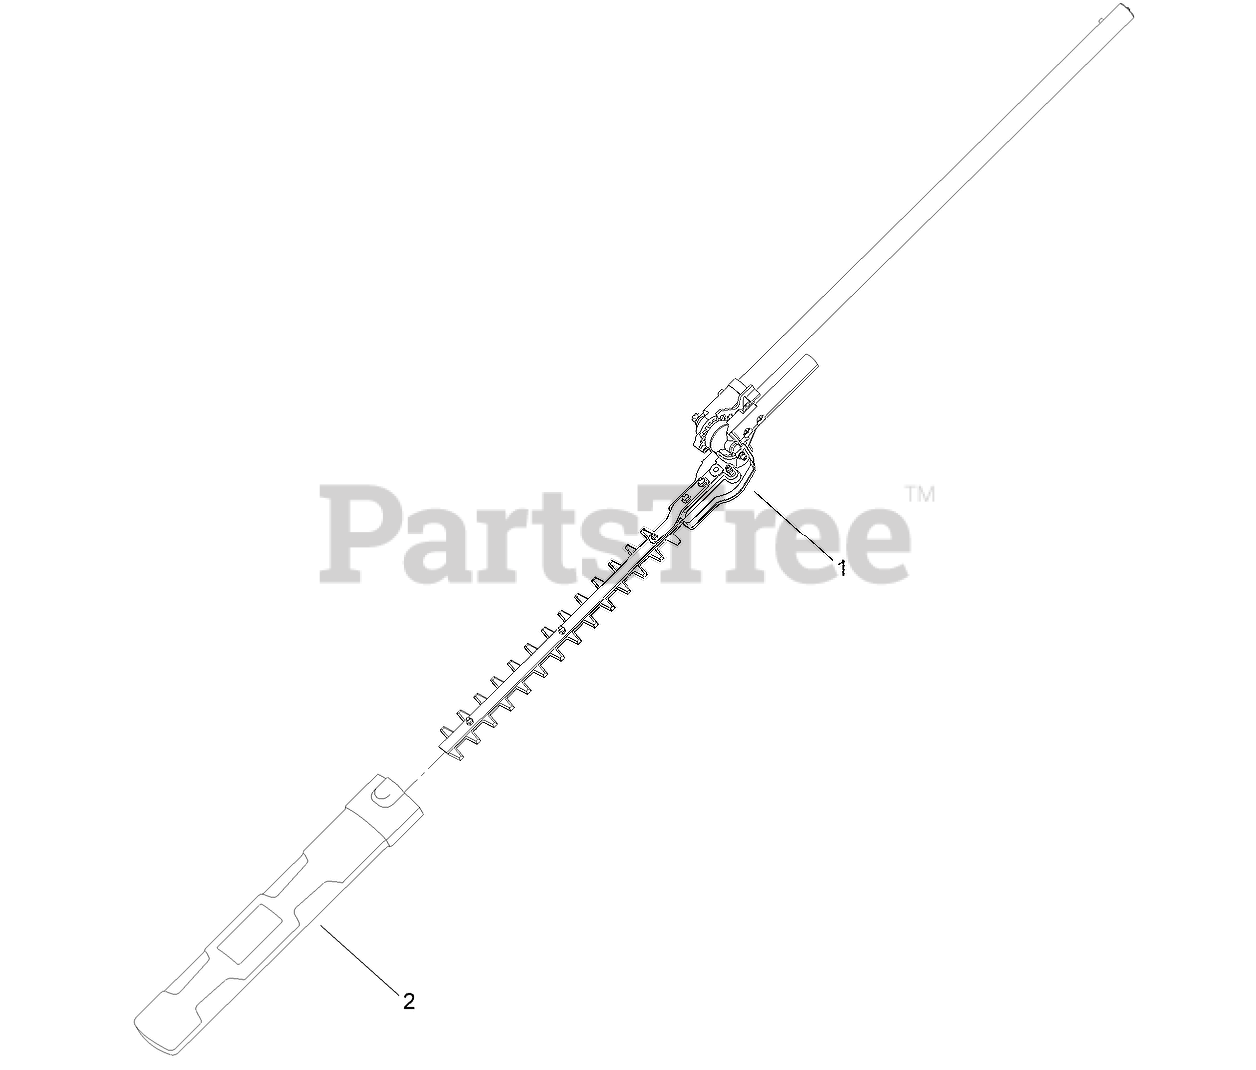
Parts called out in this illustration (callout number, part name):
1	TRIMMER-HEDGE
2	GUARD-TRIMMER, HEDGE
3	SHOULDER STRAP
